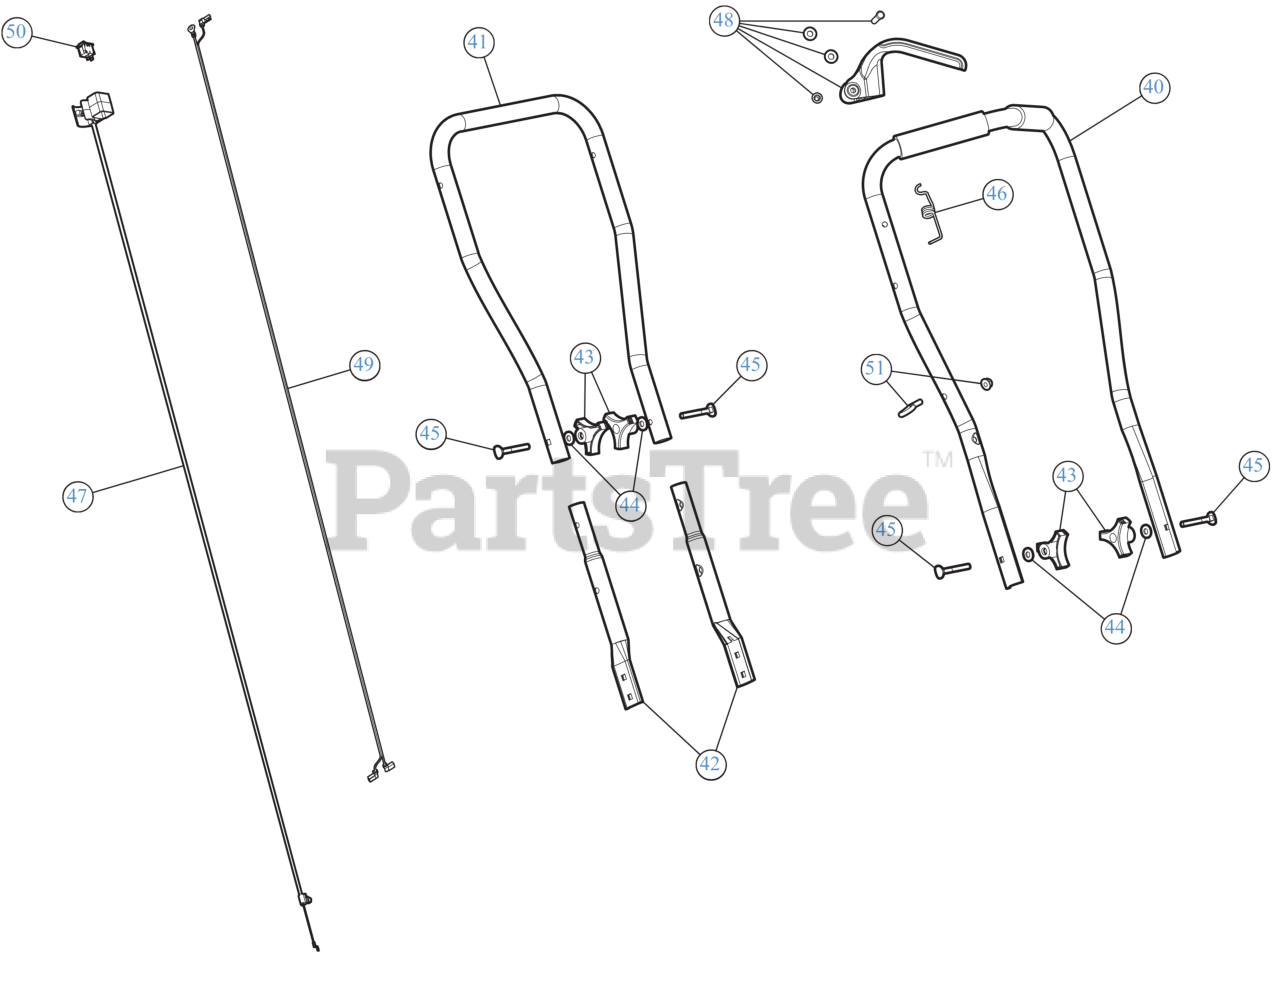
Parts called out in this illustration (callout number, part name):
40	HANDLE UP
41	HANDLE MID
42	HANDLE EXT
43	KNOB, 3-PRONG ¼ "-
44	WASH, FLAT SPECIAL
45	BOLT, CARRIAGE CRV
46	SPRING
47	THROTTLE CABLE
48	THROTTLE LEVER
49	WIRE LEAD
50	SW, MOMENTARY ON/O
51	ROPE GUIDE
